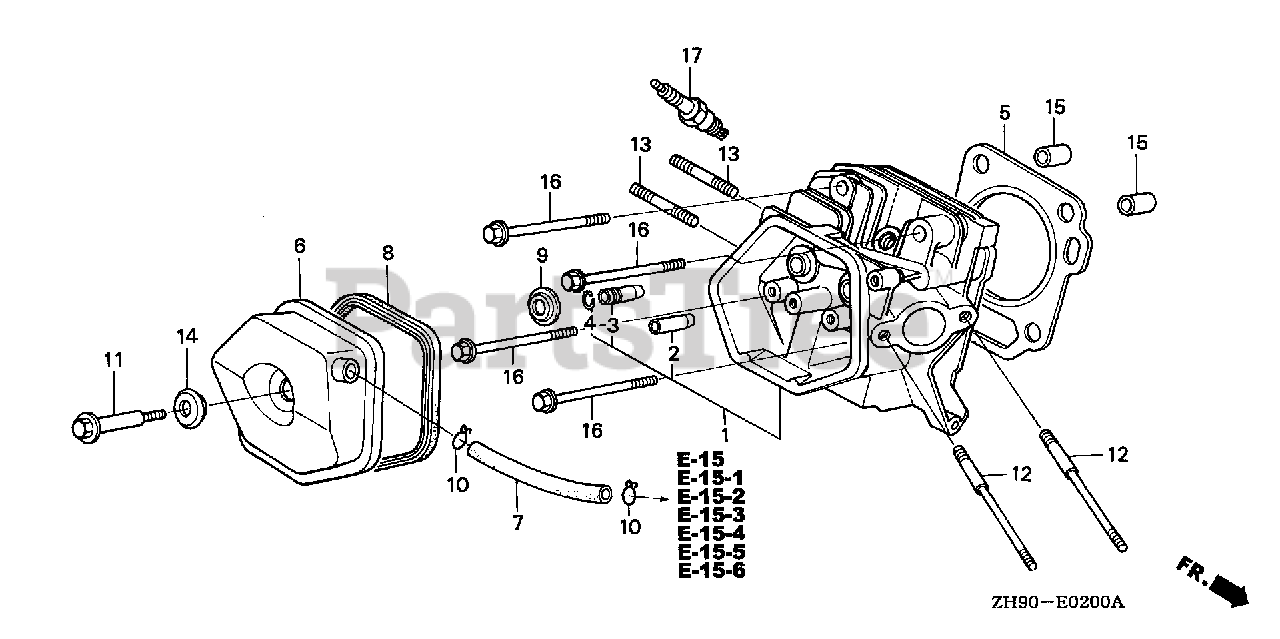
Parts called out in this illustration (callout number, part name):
1	CYLINDER HEAD
2	GUIDE, VALVE (OS)
3	GUIDE, EX. VALVE (OS)
4	CLIP, VALVE GUIDE
5	GASKET, CYLINDER HEAD
6	COVER, HEAD
7	BULK HOSE, VACUUM (11X1000) (Honda Code 4537312). (11X105)
8	GASKET, CYLINDER HEAD COVER
9	SEAT, VALVE SPRING
11	BOLT, HEAD COVER
12	BOLT, STUD (8X123)
13	BOLT 2, STUD (8X32)
14	WASHER, HEAD COVER
15	PIN A, DOWEL (12X20)
16	BOLT, FLANGE (10X80)
17	SPARK PLUG (BPR5ES) (NGK)
17	SPARK PLUG (W16EPR-U) (DENSO)
17	SPARK PLUG (BPR6ES) (NGK)
17	SPARK PLUG (W20EPR-U) (DENSO)
